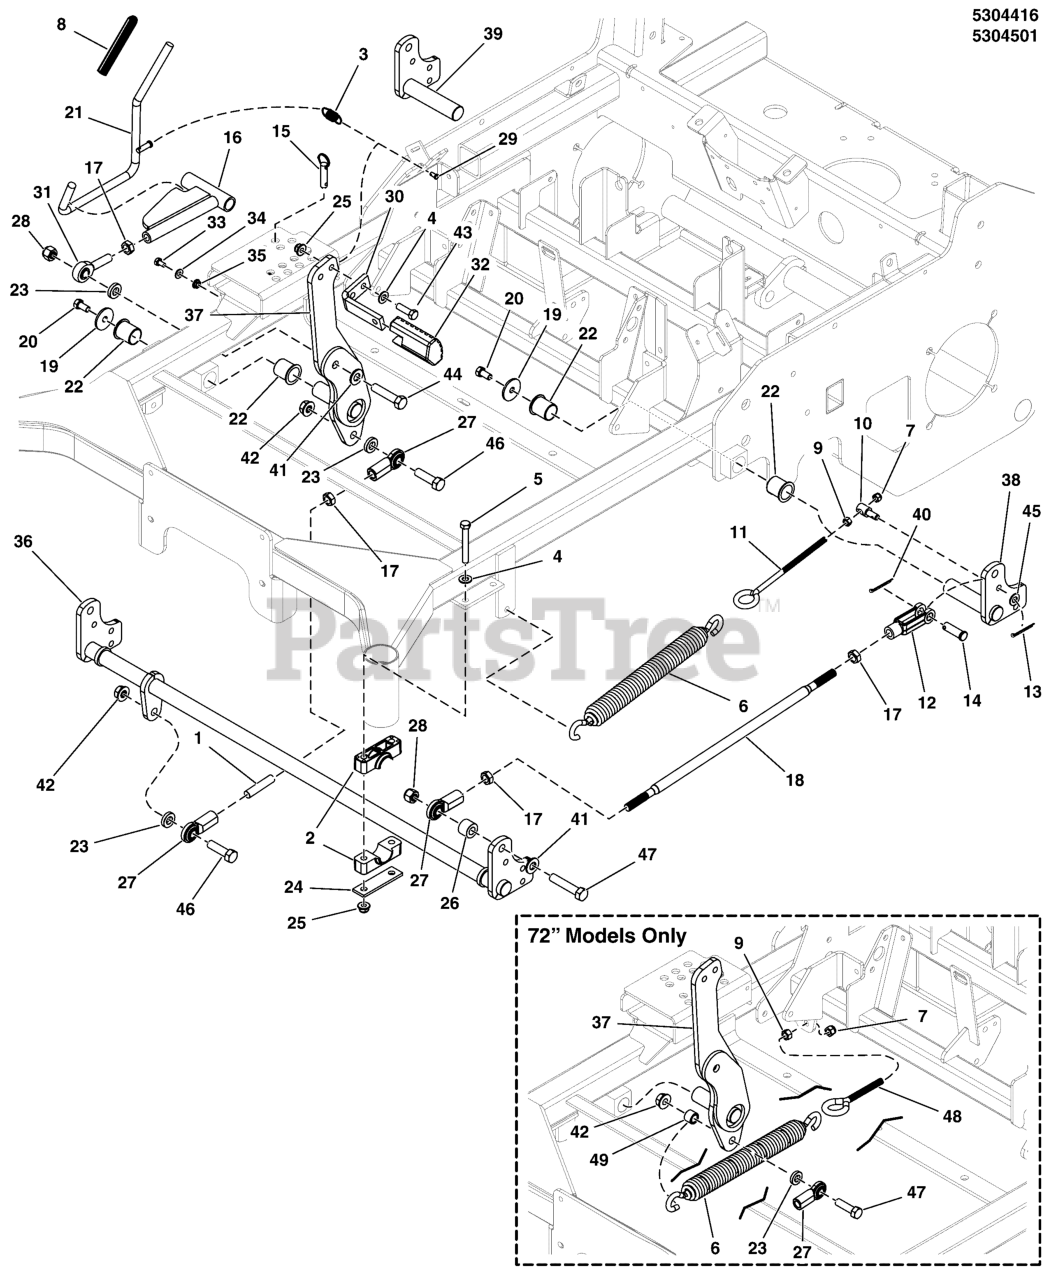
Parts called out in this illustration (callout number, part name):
1	ROD, THREADED, 1/2-20 X 2.25
2	PIVOT BLOCK, PLASTIC
3	SPRING-EXT, .740 ODX2.025LGX.072WR, BLK
4	WASHER, 3/8 SAE
5	BOLT, 3/8-16 X 2-3/4" GD5 CZ
6	SPRING-EXT, 1.393 ODX13.25LGX.218WR, BLK
7	NUT, 3/8-16 HEX NYLON LOCK
8	GRIP, FOAM, .475 X 4.35 X .095
9	NUT, 3/8-16 HEX
10	ADJUSTER, DECK HANGER
11	EYE BOLT, 3/8-16 X 8, 3THRD, 1EYE, CZ
12	CLEVIS, 1/2-20, STEEL, CLEAR ZINC
13	PIN, COTTER, 1/8 X 3/4
14	PIN, CLEVIS, 1/2 X 1-23/64, PLATED
15	PIN, HITCH, 1/2 X 2.00 OAL, CZ
16	WELD, DECK ADJUST LINK - RED
17	NUT, 1/2-20 HEX JAM
18	ROD, DECK LIFT, 19.25, CZ
19	WASHER, .390 X 1.50 X .109, CZ
20	BOLT, 3/8-16 X 3/4, PLT W/PATCH
21	WELD, ROD DECK LIFT, F320Z - BLK
22	BUSHING, 1.00 X 1.13 X 1.38, PLASTIC
23	SPACER, .52 X 1.00 X .22, PM, CZ
24	PLATE, PIVOT BLOCK SUPPORT - BLK
25	NUT, 3/8-16 HEX NYLOCK FLANGE
26	SPACER, .52 X 1.00 X .75, CZ
27	JOINT-BALL .500-20 THD .500ID, CLR ZINC
28	NUT, 1/2-13 HEX NYLON LOCK
29	PIN, CLEVIS, 1/4 X 1/2, PLATED
30	PEDAL, FOOT - BLK
31	BALL JOINT, 1/2-20, MALE
32	PEDAL, Rubber
33	HHCS, 1/4-20 X 0.625, GR5, ZINC/CLEAR
34	WASHER, 1/4 SAE
35	NUT, 1/4-20 HEX SERR. FLANGE
36	WELD, DECK LIFT SHAFT, F320-61" - RED
37	WELD, DECK LIFT PEDAL, F320Z - RED
38	WELD, DECK LIFT LEVER, F320Z, LH - RED
39	WELD, DECK LIFT LEVER, F320Z, RH - RED
40	PIN, COTTER, 1/8 X 1-1/4
41	WASHER, 1/2 SAE
42	NUT, Hex Flange, Nylock, 1/2-13
43	BOLT, 3/8-16 X 1-1/4" GD5 CZ
44	BOLT, 1/2-13 X 2-1/4" GD5 CZ
45	WASHER, 3/8 GD.9 FLAT
46	BOLT, 1/2-13 X 2" GD5 CZ
47	BOLT, 1/2-13 X 2-1/2" GD5 CZ
48	EYE BOLT, 3/8-16 X 5, 2.88THRD, 1EYE, CZ
49	SPACER, .51 X .75 X .56, PM, CZ
